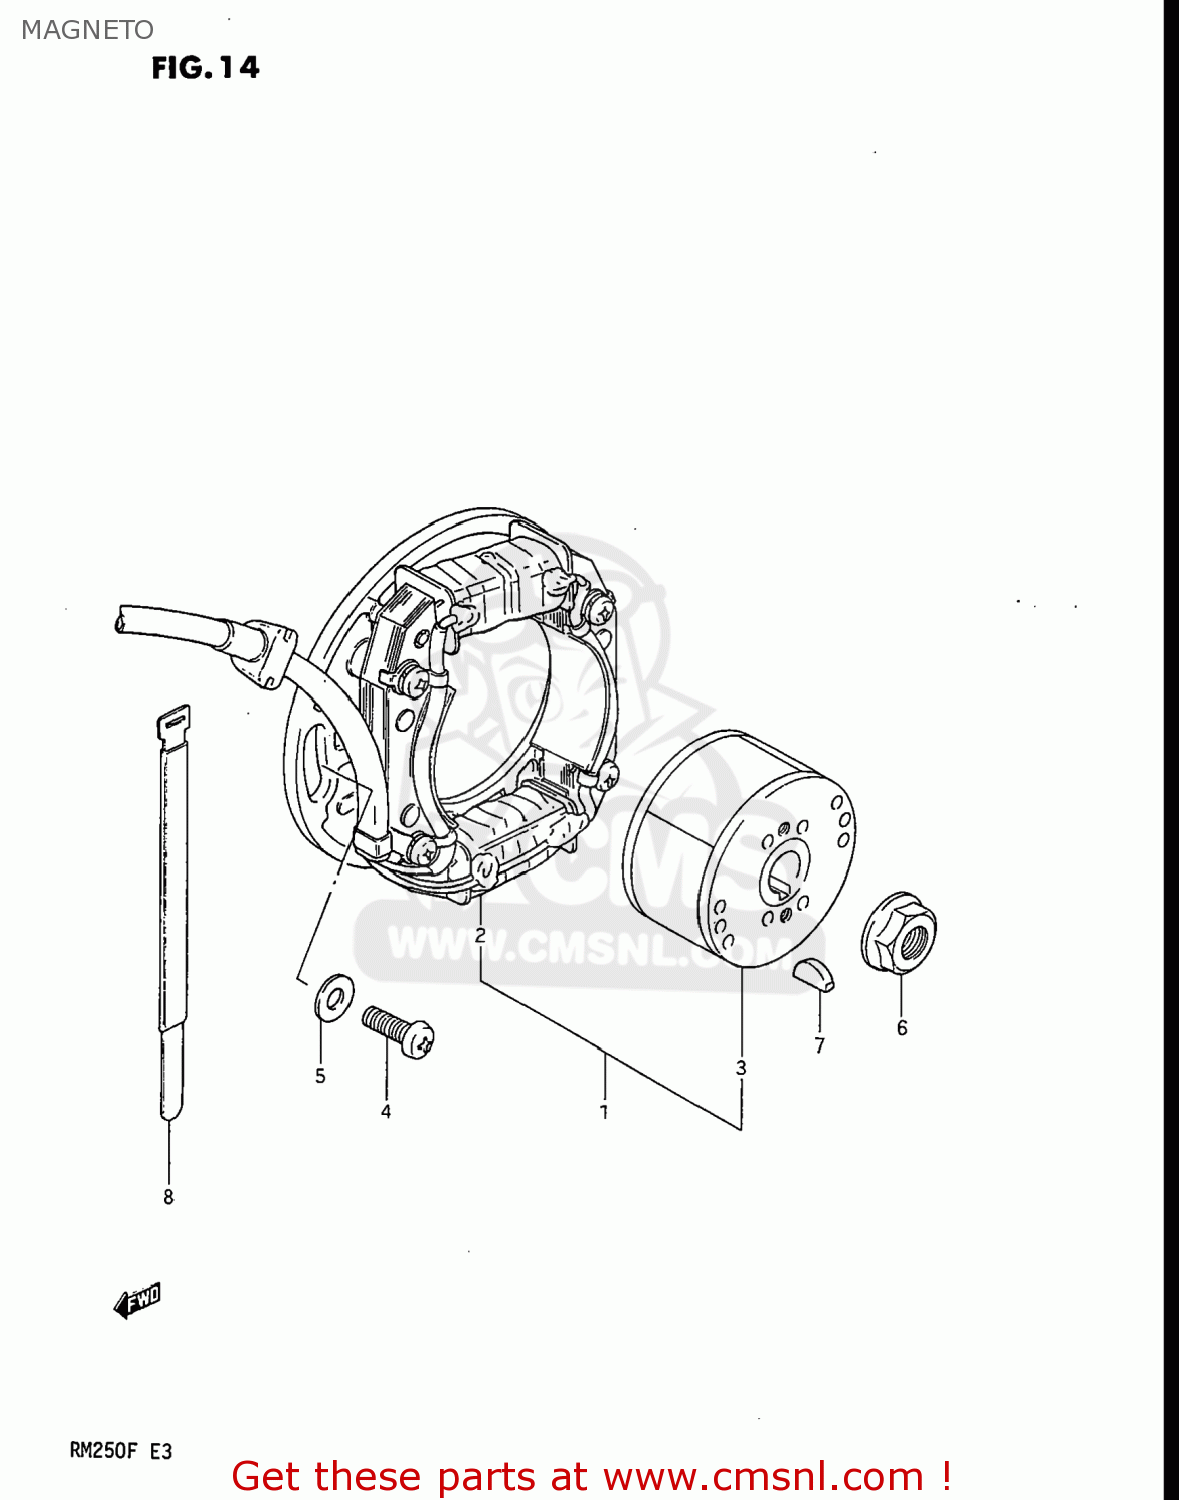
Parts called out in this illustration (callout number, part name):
1	MAGNETO ASSEMBLY
2	STATOR ASSEMBLY
3	ROTOR,FLYWHEEL
4	SCREW
5	WASHER
6	NUT
7	KEY 4MM
8	CLAMP
